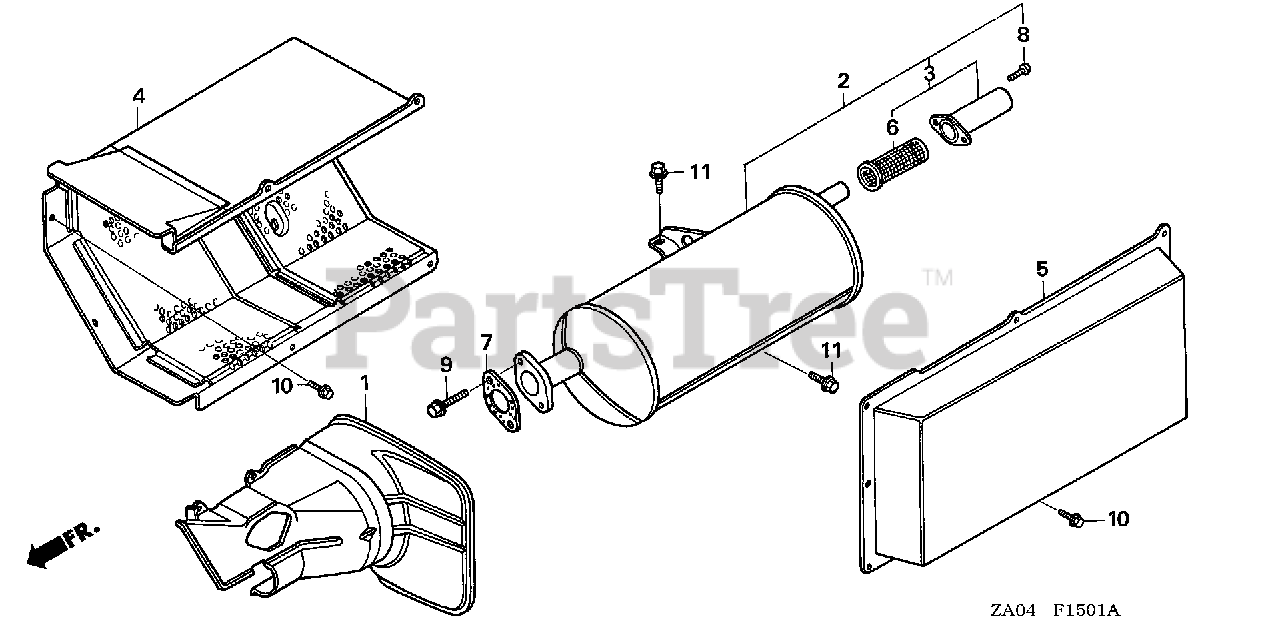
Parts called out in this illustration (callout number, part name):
3	CAP SET, ARRESTER
3	CAP SET, ARRESTER (NOT AVAILABLE)
4	SEPARATOR A, MUFFLER
5	SEPARATOR B, MUFFLER
6	ARRESTER, SPARK
7	GASKET, MUFFLER
8	SCREW, PAN (5X8)
9	BOLT, FLANGE (8X20)
10	BOLT, FLANGE (6X10)
11	BOLT, FLANGE (8X20)
